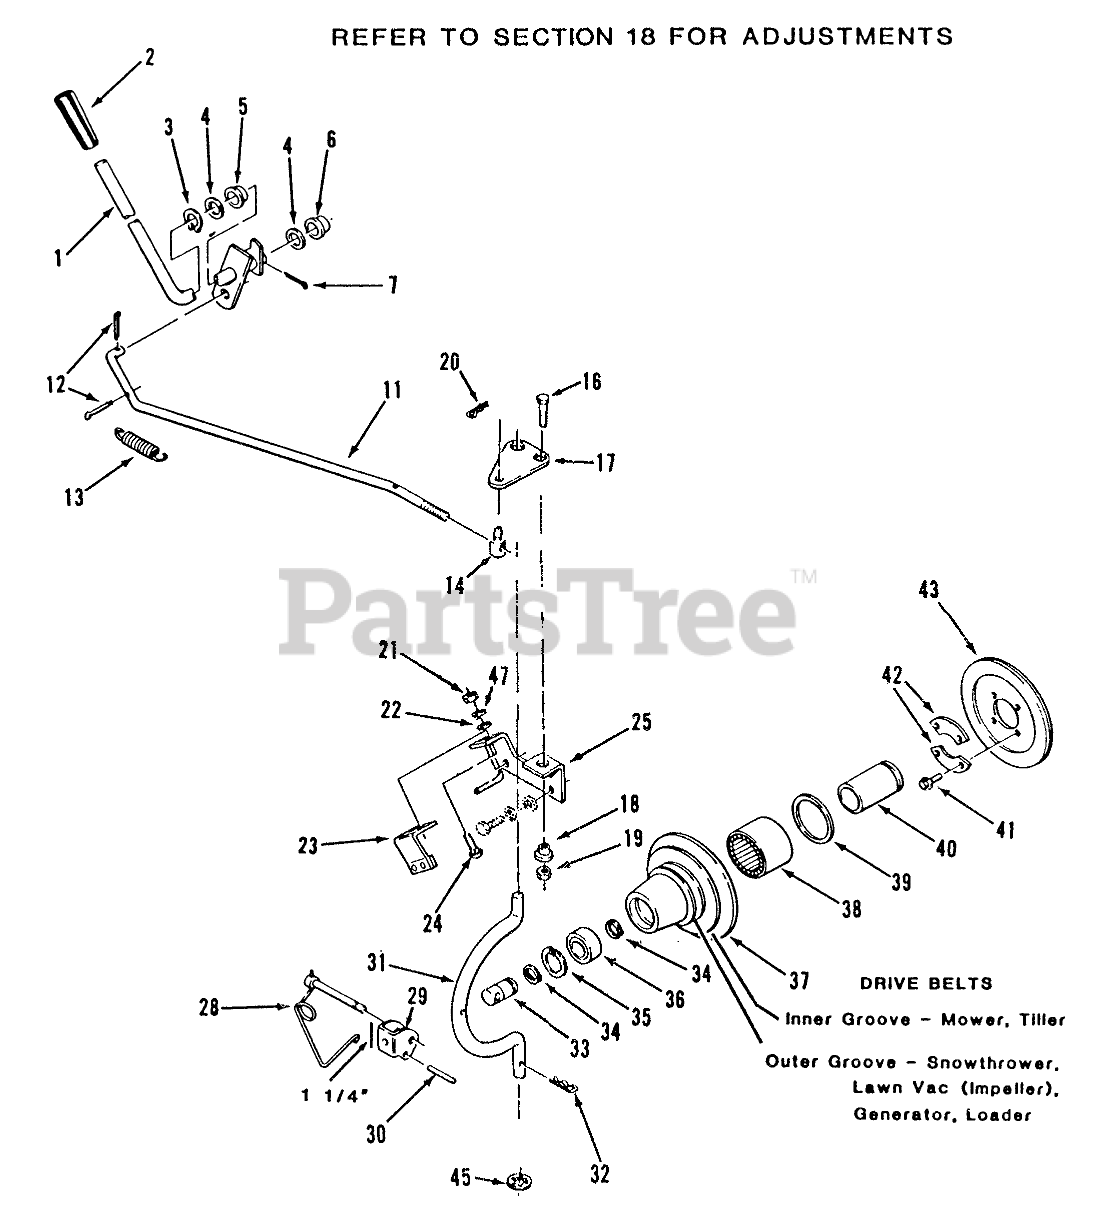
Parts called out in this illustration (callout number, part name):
1	ASSY PTO CLUTCH LEVE
2	GRIP
3	Grip Ring
4	SHIM-WASHER
5	BUSHING-NYLINER
6	NYLINER BUSHING
7	Pop Rivet
11	ROD-PTO CLUTCH
12	Pop Rivet
13	SPRING
14	TRUNNION
16	BOLT
17	PLATE
18	SPACER-LIFT LINK
19	Nut
20	Hairpin Cotter
21	Nut
23	ASM-Bracket
24	Bolt-Carriage
25	Engine Bracket C-161 Twin Only
28	LOCKING PIN ASM
29	CLEVIS B
31	ROD HOUSING
32	Hairpin
33	SHAFT-PTO
34	RING-SNAP, EXTERNAL
35	Ring-Snap
36	BEARING-BALL
37	Housing-Clutch
38	BRG-NEEDLE OPEN END
39	SEAL-OIL
40	RACE-BEARING
41	H H C S
42	RETAINER
43	Clutch Plate & Facing
45	RING-REINFORCED CIRC
47	Washer
